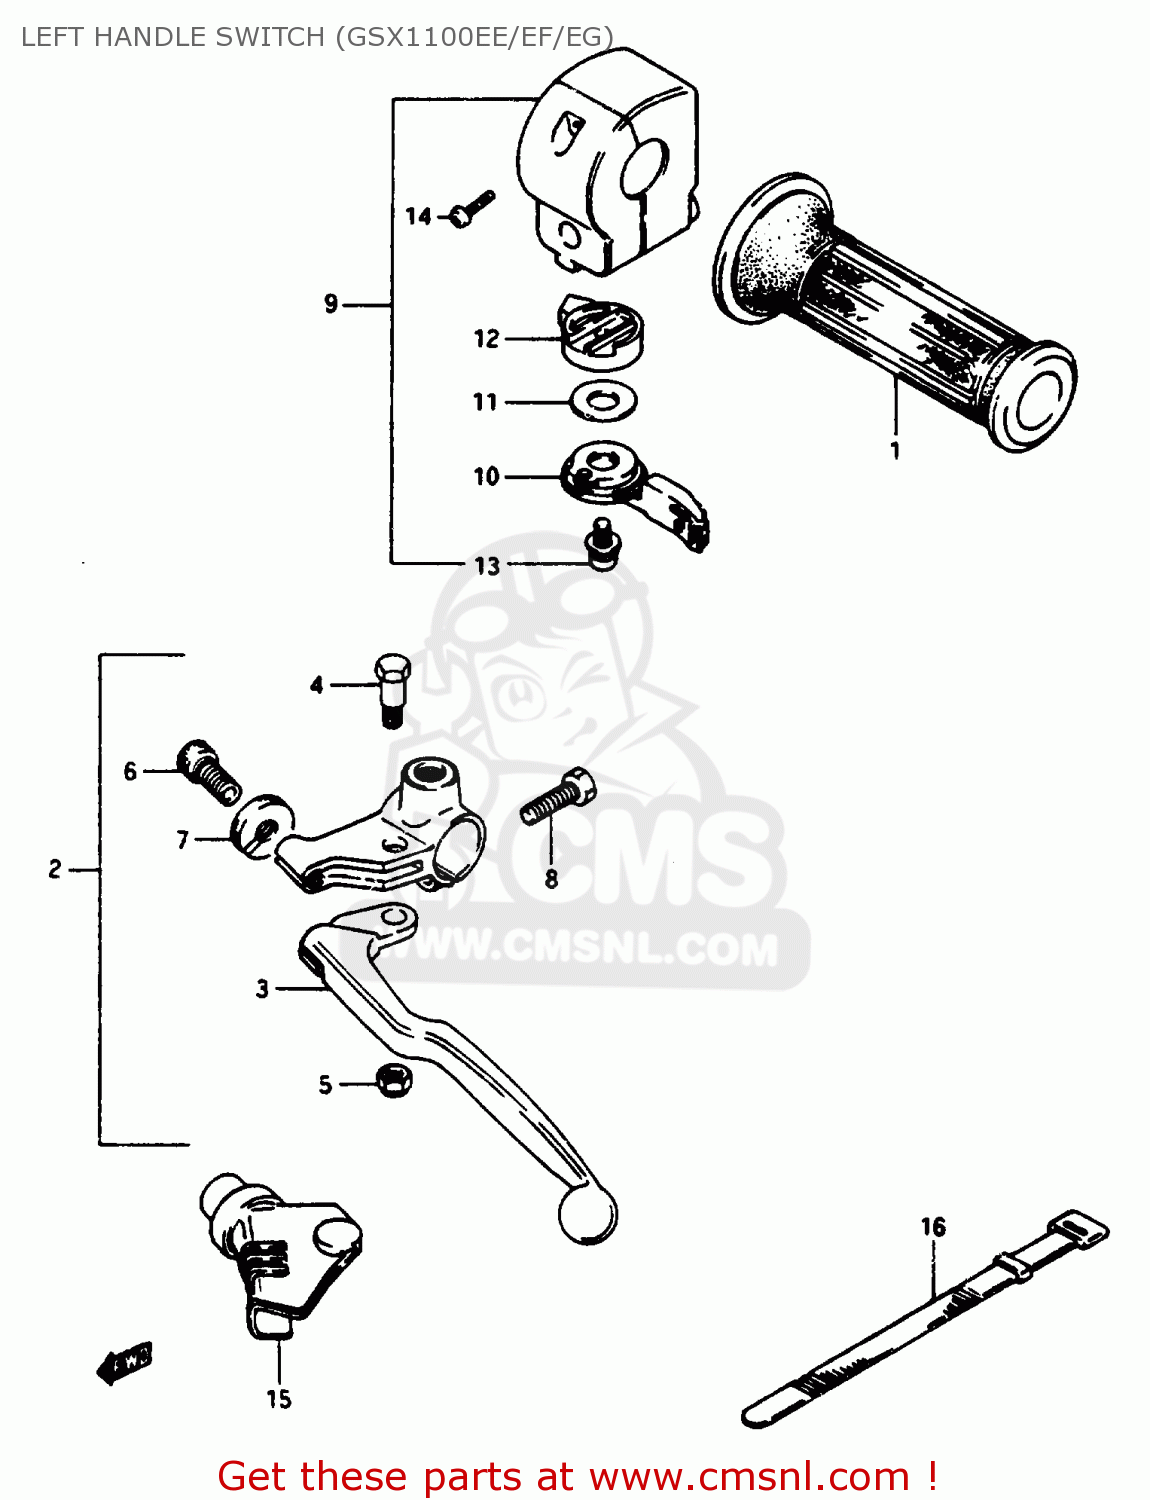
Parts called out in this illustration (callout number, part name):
1	GRIP,L
2	LEVER ASSY,CLU
3	LEVER,CLUTCH
4	BOLT,LEVER
5	NUT
6	ADJUSTER,CABLE
7	NUT,CABLE ADJUSTER
8	BOLT
9	SWITCH ASSY, HANDLE LH
10	LEVER,STARTER
11	WASHER,ADJUSTER
12	BODY,STARTER LEVER
13	SCREW,CHOKE LE
14	SCREW
15	COVER,CLUTCH LEVER
16	CLAMP(L:120)
